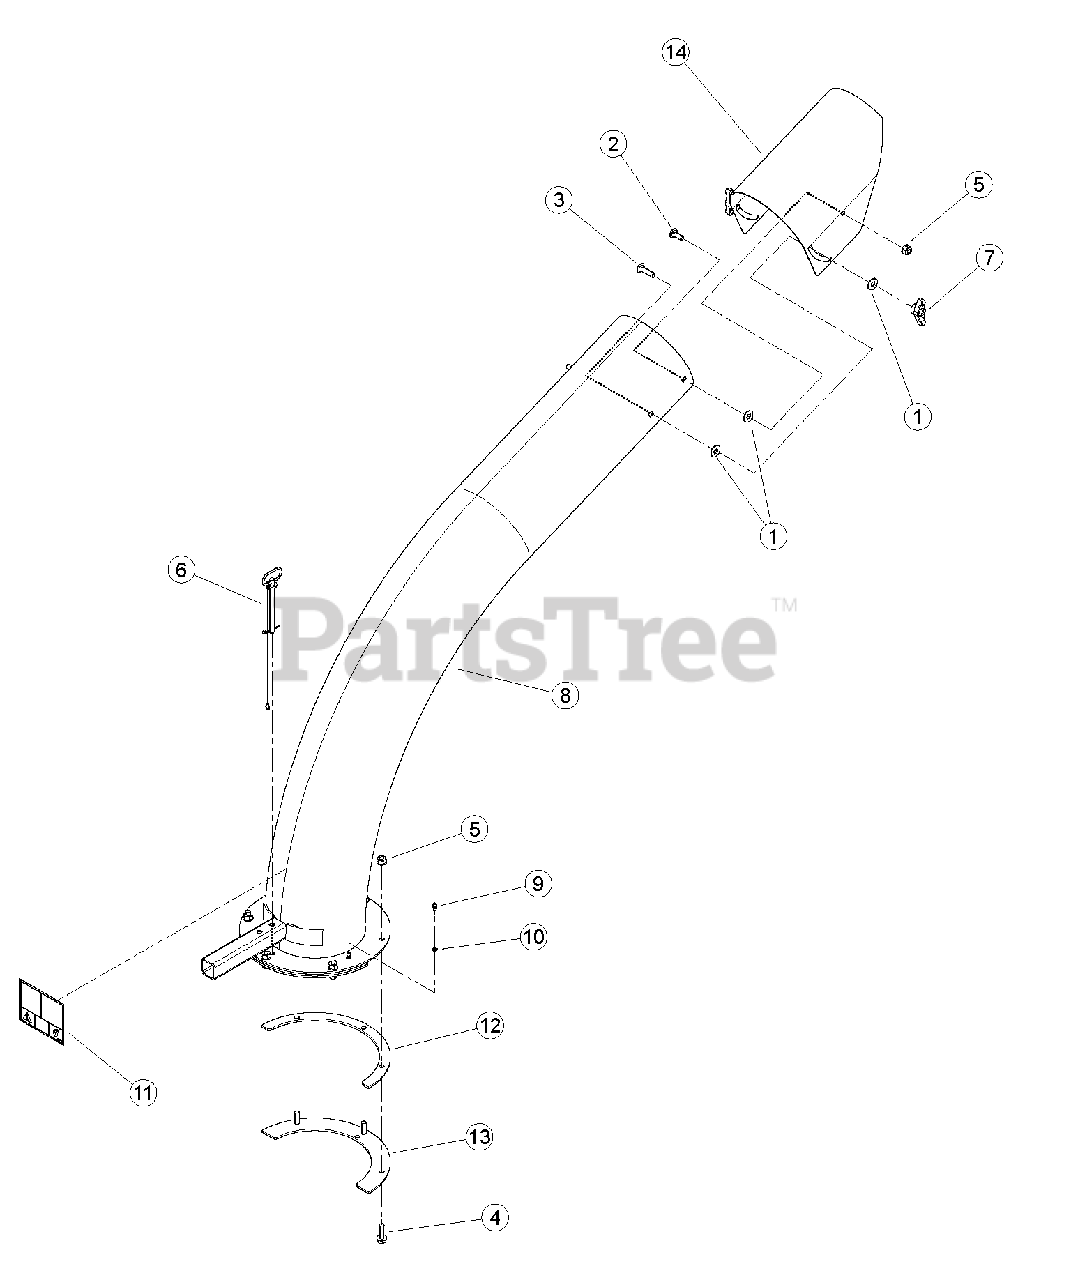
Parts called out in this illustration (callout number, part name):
1	WASHER, 3/8" FLAT ZP
2	BOLT, 3/8 X 1" GR5 CRG NC ZP
3	BOLT, 3/8 X 1-1/2" GR5 CRG NC ZP
4	BOLT, 3/8 X 1-1/4 FLANGE NC
5	NUT, 3/8-16 NYLOCK FLANGE
6	PIN, 3/8 X 4.25" DISCHARGE
7	KNOB, 3/8-16 UNC FEMALE TEE
8	ASSEMBLY, 8 INCH DISCHARGE CHUTE
9	FITTING, 1/4 SELF-TAP GREASE
10	WASHER, FLAT .254X.400X.048
11	DECAL, DISCHARGE DEBRIS & LOCK
12	RING, DISCHARGE SPACER
13	RING, DISCHARGE CLAMP
14	CAP, 8 INCH DISCHARGE CHUTE
